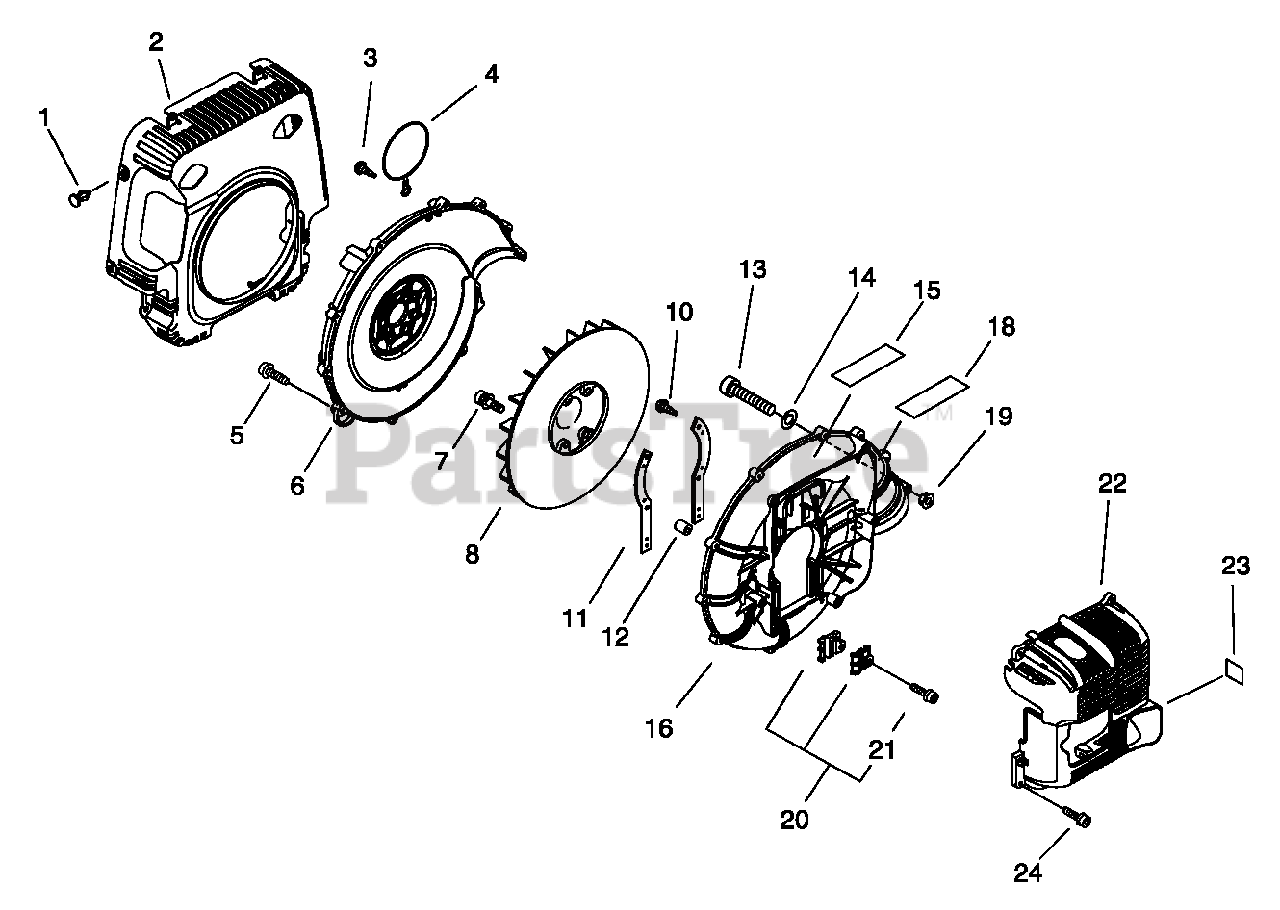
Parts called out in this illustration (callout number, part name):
2	GUARD, DEBRIS
3	SCREW - 5X16
4	STOPPER
5	SCREW - 5X25 -- TAPPING
6	COVER, FAN - INNER
7	SCREW - 5X20
10	SCREW - 3X12 -- TAPPING
11	BRACKET, ENGINE
12	COLLAR - 6
13	SCREW - 5X60
14	WASHER - 5
15	LABEL - MODEL
16	COVER, FAN - OUTER
18	LABEL - CAUTION
19	NUT - 5 -- FLANGE
20	CABLE BRACKET KIT
21	SCREW - 5X25 -- TAPPING
22	COVER, ENGINE
23	LABEL - CAUTION
24	SCREW - 5X20 -- TAPPING
